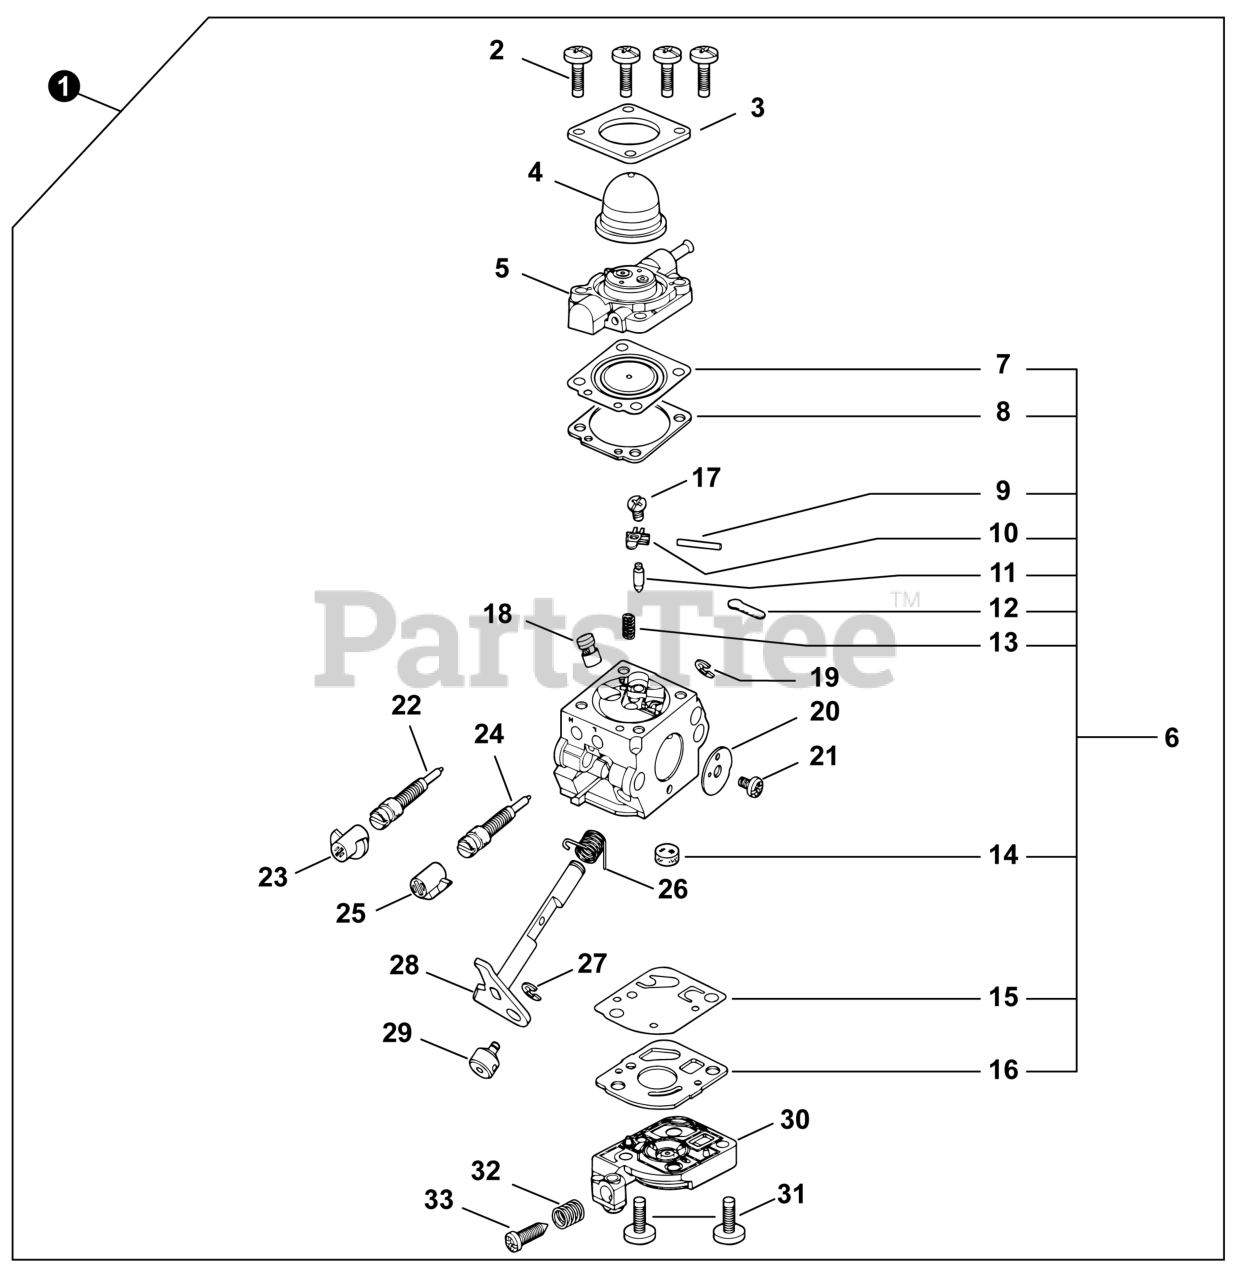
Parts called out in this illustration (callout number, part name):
1	CARBURETOR - C1U-K82
3	RETAINER, PURGE BULB
4	BULB, PURGE
5	BODY ASSY, PURGE
6	REPAIR KIT, CARBURETOR
7	DIAPHRAGM, METERING
8	GASKET, METERING DIAPHRAGM
9	PIN, METERING LEVER
10	LEVER, METERING
11	VALVE, INLET NEEDLE
12	PLUG, WELCH
13	SPRING, METERING LEVER
14	STRAINER
15	DIAPHRAGM, PUMP
16	GASKET, PUMP
18	NOZZLE, CHECK VALVE
20	VALVE, THROTTLE
22	NEEDLE, HIGH SPEED
23	CAP, LIMITER - RED
24	NEEDLE, MIXTURE
25	CAP, LIMITER - WHITE
26	SPRING, THROTTLE RETURN
28	SHAFT ASSY, THROTTLE
30	COVER, FUEL PUMP
33	SCREW, THROTTLE ADJUST
